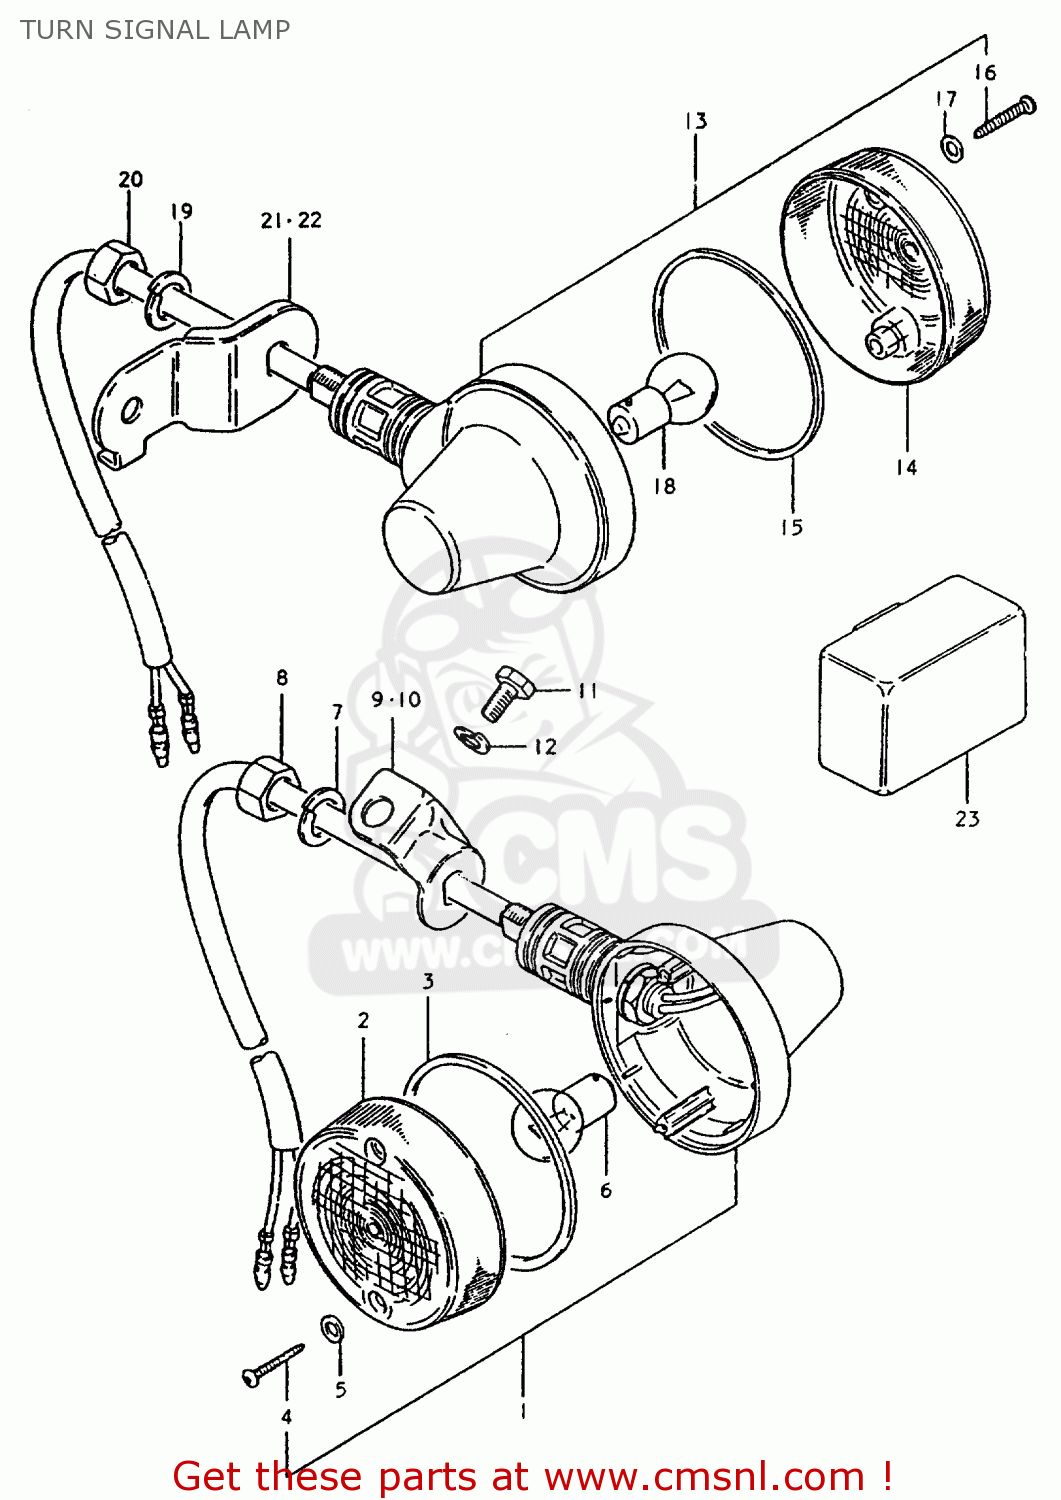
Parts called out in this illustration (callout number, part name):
1	LAMP ASSY,RR TURNSIGNAL
2	LENS
3	GASKET (NAS)
4	SCREW TAPP.
5	GASKET (NAS)
6	BULB(6V/10W,STANLEY,A4117)
7	WASHER,LOCK 12
8	NUT
9	BRACKET,TURNSIGNAL LAMP,R
10	BRACKET,TURNSIGNAL LAMP,L
11	BOLT
12	LOCK WASHER
13	LAMP ASSY,RR TURNSIGNAL
14	LENS
15	GASKET (NAS)
16	SCREW TAPP.
17	GASKET (NAS)
18	BULB(6V/10W,STANLEY,A4117)
19	WASHER,LOCK 12
20	NUT
21	BRACKET,REAR TURN SIGNAL
22	BRACKET,REAR TURN SIGNAL
23	RELAY, TURN SIGNAL
